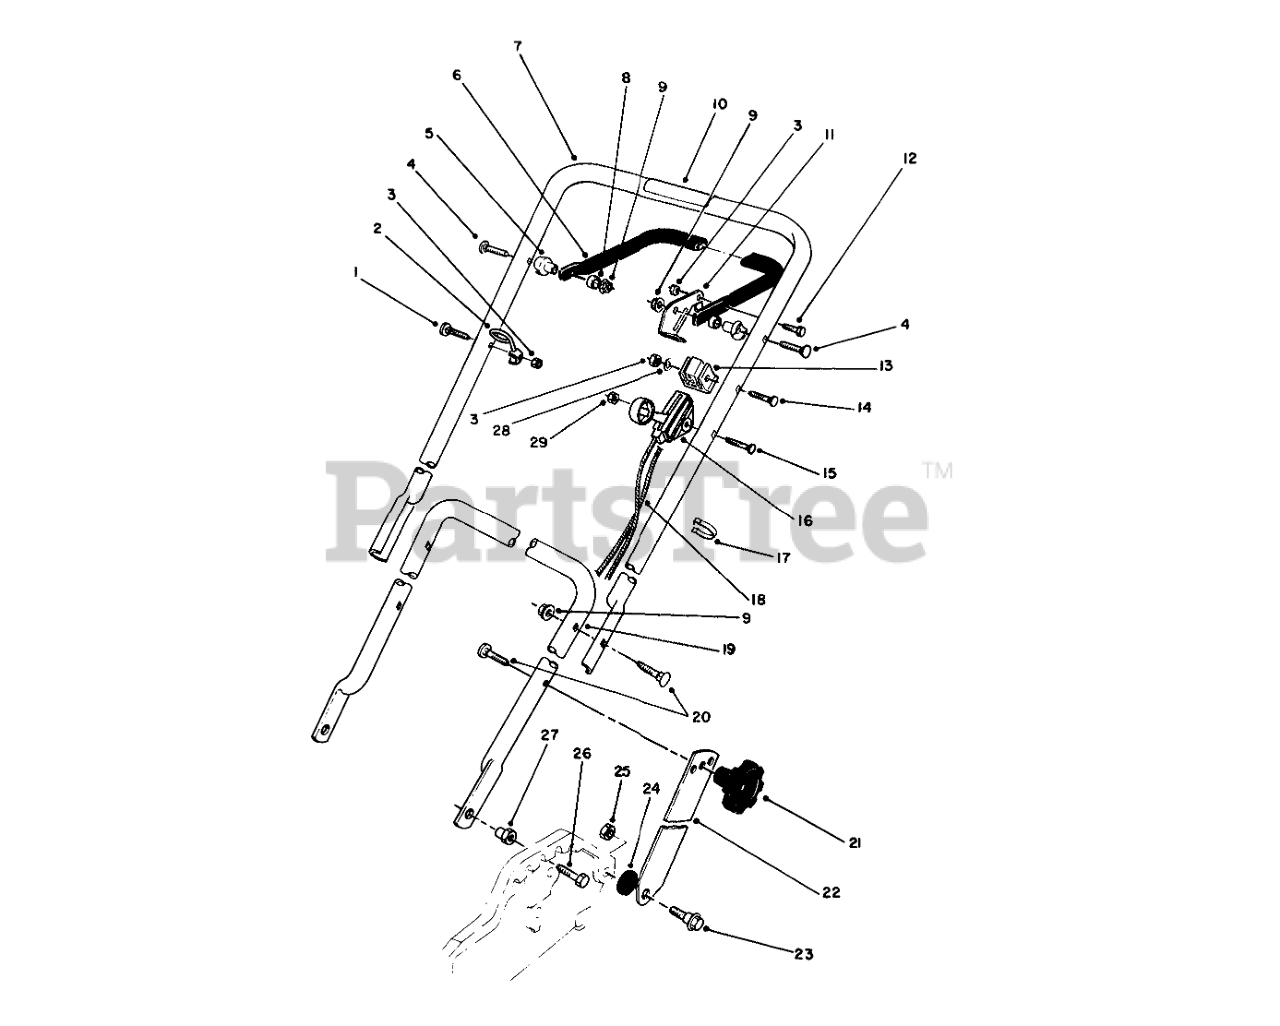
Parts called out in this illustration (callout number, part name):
1	HANDLE SCREW
2	Guide
3	NUT-LOCK, NI
4	5/16-18 X 2 HNDLE SCREW
5	SPACER-SUPPORT
6	Bar-Control
7	Handle-Upper (Incl. Ref. #10)
8	SPACER-NYLON
9	NUT-LOCK, NI
10	Decal-Danger
11	LEVER-CONTROL
12	SCREW-HH
13	SUPPORT-CABLE
14	HANDLE SCREW
15	SCREW-HANDLE
16	THROTTLE CONTROL
17	BOWDEN CLIP
18	BRAKE CABLE
19	LOWER HANDLE
20	SCREW
22	Handle Latch
23	SCREW-SHOULDER
24	SPACER
25	NUT-LOCK, NI
26	SCREW-HH
27	HANDLE PIVOT NUT
28	WASHER-FLAT
29	NUT-LOCK, NI
